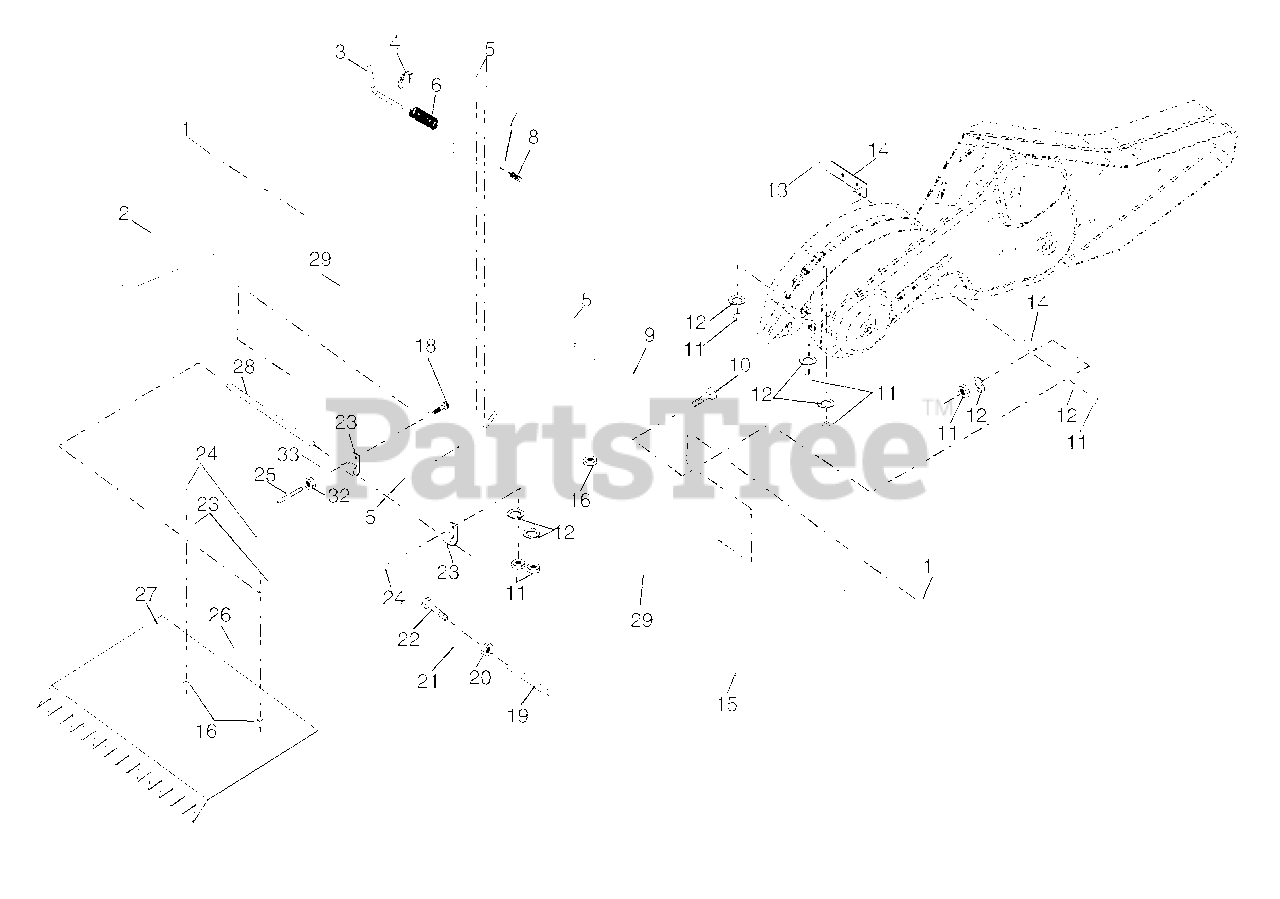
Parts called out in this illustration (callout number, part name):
1	Nut, Flange 5/16-18
2	Shield, Side, Outer L. H.
3	Pin, Stake, Depth
4	Ring, Klip
5	Bolt, Carriage 5/16-18 x 3/4
6	Spring
7	Bracket, Latch
8	Spring, Depth Stake
10	Bolt, Carriage 5/16-18 x 1
11	Nut, Hex 5/16-18
12	Washer, Lock 5/16
13	Bolt, Carriage 5/16-18 x 1-1/4
14	Bracket, Shield Tine
15	Shield, Side, Outer R.H.
16	Nut, Hex Flange 1/4-20 UNC
18	Bolt, Carriage 1/4-20 x 1-1/4 Gr. 5
19	Grip
20	Nut, Hex 3/8-16
21	Stake, Depth
22	Bolt, Hex 3/8-16 x 2
23	Hinge
24	Bolt, Carriage 1/4-20 x 1/2 Gr. 5
25	Cap, Vinyl
26	Pad, Idler
27	Shield, Leveling
28	Pin, Hinge
29	Shield, Side
32	Nut Fin Hex 1/4-20 UNC
33	Washer Lock Hvy Helical 1/4
